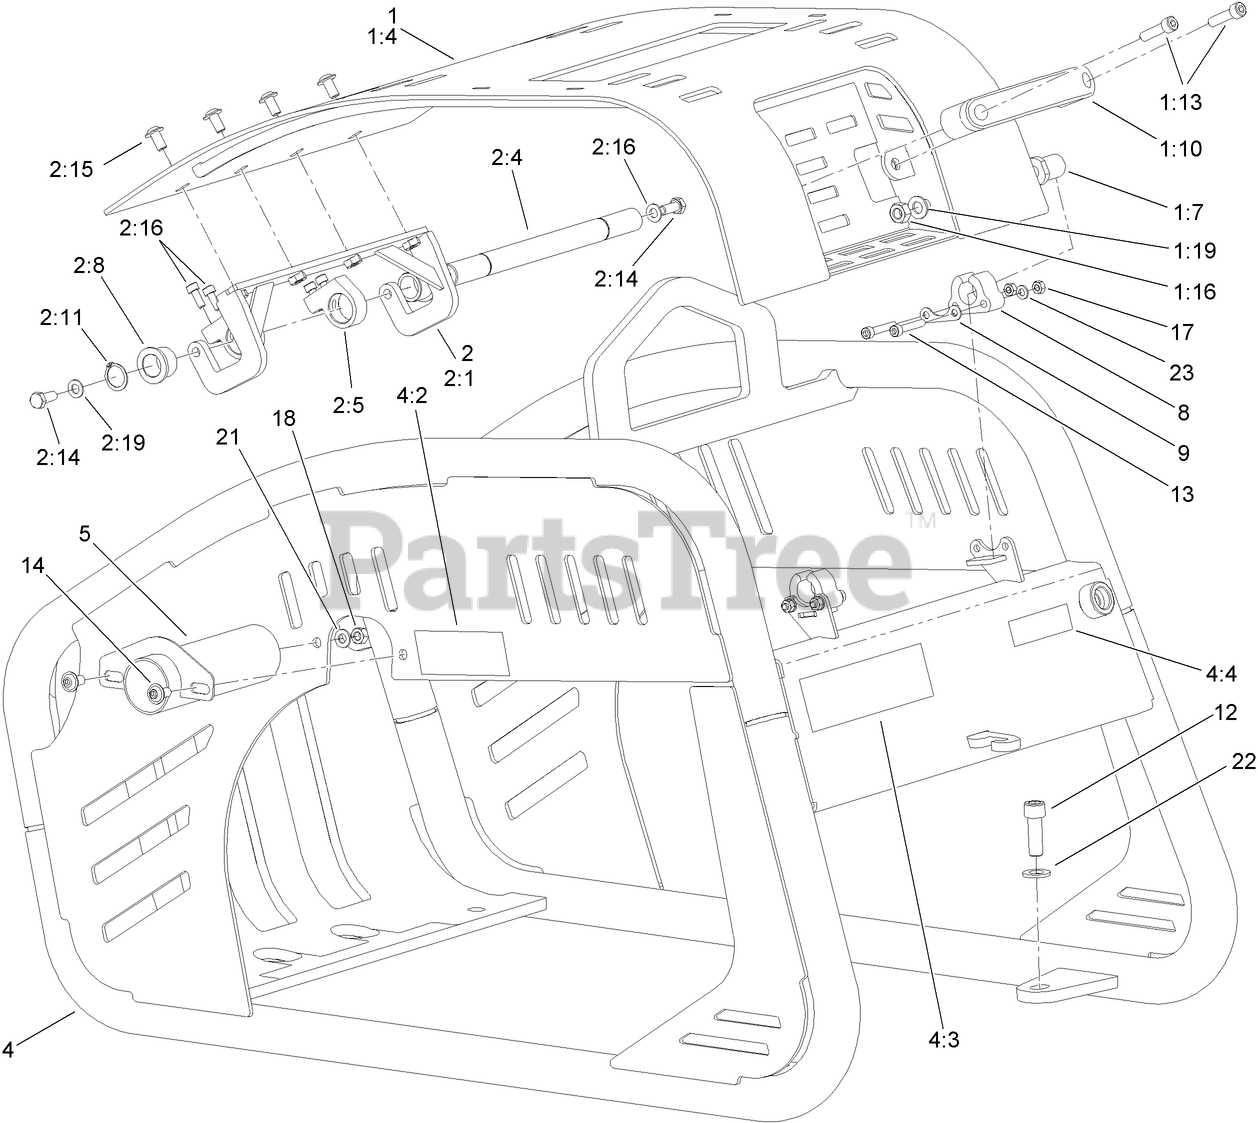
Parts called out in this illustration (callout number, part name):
1	TOP COVER ASM
1:7	PIN-HANDLE
1:10	HANDLE
1:16	NUT-LOCK, NI
1:19	WASHER
2	SHAFT AND FRONT BRACKET ASM
2:1	BRACKET-FRONT
2:5	EYE-FRONT
2:8	BUSHING
2:11	RING-SEALING
2:19	WASHER
4	FRAME ASM
4:2	DECAL-SURFACE, HOT
4:3	DECAL-WARNING, PLATE
4:4	DECAL-ARRESTER, SPARK
5	EXHAUST
8	SECURING-COVER
9	WASHER-SECURING
21	WASHER
22	WASHER
23	WASHER
